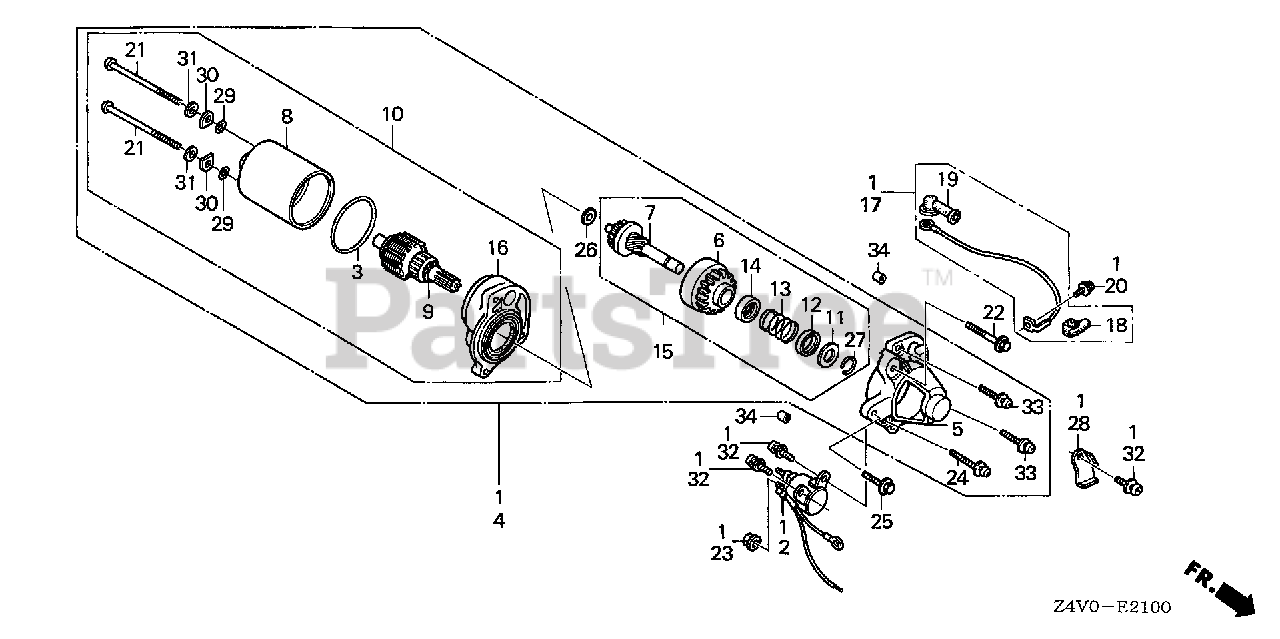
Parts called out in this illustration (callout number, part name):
1	STARTER MOTOR ASSY.
2	SWITCH, STARTING MAGNET
4	STARTER MOTOR UNIT (SM-11205) (181MM)
5	COVER, GEAR
6	PINION ASSY.
7	SHAFT UNIT, GEAR
8	YOKE ASSY.
9	ROTOR ASSY.
10	MOTOR ONLY
11	PIECE A, STOPPER
12	PIECE B, STOPPER
13	SPRING, RETURN
14	COVER, SPRING
15	GEAR ASSY.
16	BRACKET, FR.
17	WIRE, MAGNETIC SWITCH
18	COVER, MAGNETIC SWITCH
19	COVER, STARTER MOTOR TERMINAL
20	SCREW-WASHER (5X8)
21	BOLT, SETTING
22	BOLT, FLANGE (6X32) (CT200)
23	NUT-WASHER (6MM)
24	SCREW-WASHER (5X30)
25	BOLT, FLANGE (6X25) (CT200)
26	WASHER, PINION
27	CIRCLIP (10.2MM)
28	HOLDER, HARNESS
30	WASHER, SPECIAL
31	WASHER, SPRING
32	SCREW-WASHER (5X14)
33	SCREW-WASHER (5X20)
34	PIN, DOWEL (8X10)
